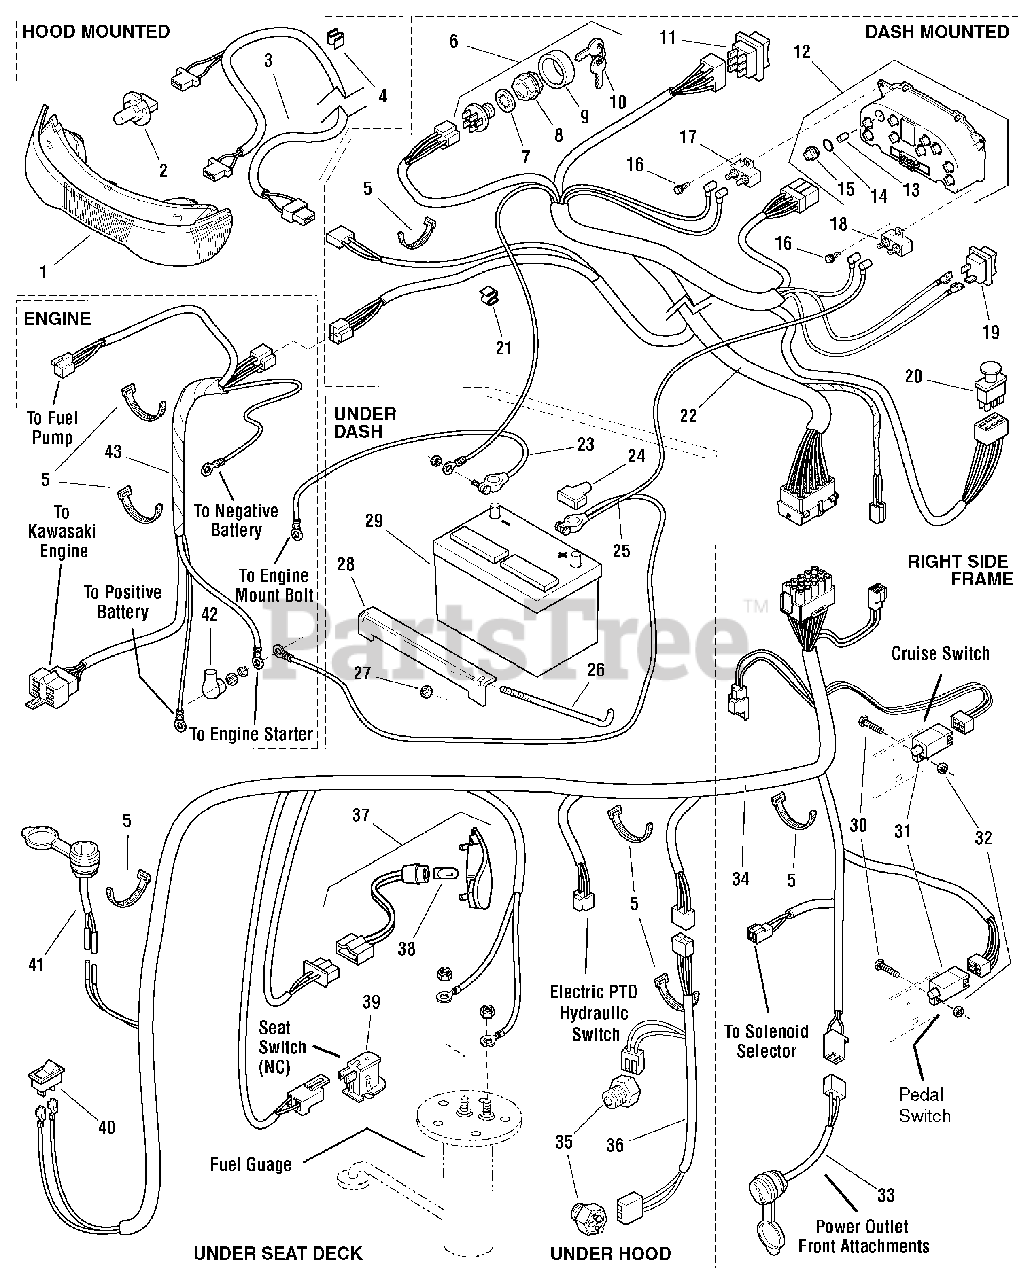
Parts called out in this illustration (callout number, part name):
1	HEADLIGHT ASSEMBLY
2	BULB, Headlight Halogen
3	HARNESS, Wiring, Headlight
4	CLIP, Wire
5	TIE, Self Locking
6	SWITCH ASSEMBLY, Ignition
7	LOCKWASHER, Internal Tooth
8	NUT, Hex, Flange, 5/8-32, Ignition Switch Die Cast
9	COVER, Ignition Switch
10	KEYS, Set of 2
11	SWITCH, Electrical Lift
12	PANEL, Instrument Air Cooled
12	PANEL, Instrument Liquid Cooled
13	BULB, Instrument Panel
14	SEAL, Lamp Socket Plug
15	HOLDER, Bulb (Includes Ref. No. 14)
16	SCREW, Hex Washer Head, 12-24 x 5/8
17	BREAKER, Circuit 12Volt, 10Amps
18	BREAKER, Circuit 12Volt, 20Amps with Tab 9/32
19	SWITCH, Headlights
20	SWITCH, PTO Push/Pull Symbols
22	HARNESS, Wiring
23	CABLE, 1 Ring, 1 Battery Terminal
24	INSULATOR, Battery Terminal
25	CABLE, 1 Ring, 1 Battery Terminal
27	NUT, Hex KEPS, 1/4-20 Conical Washer
28	BRACKET, Battery Hold Down
29	BATTERY, 12 Volt, 6 Cell, 500 Amps
30	SCREW, Hex Washer Head Slot 10-24 x 5/8
31	SWITCH, Push Button, Neutral, Start
32	NUT, Hex KEPS, 10-24
33	HARNESS ASSEMBLY, Power Outlet, 8" Long
34	HARNESS, Rear
35	SWITCH, Interlock Ball Check 5/16 Long Thread
36	HARNESS, PTO Lights
37	TAIL LIGHT ASSEMBLY
38	BULB, Tail Light
39	SWITCH, Push Button Foot Pedal
40	SWITCH, Rocker Solenoid, Select
41	OUTLET, 12 Volt
42	BOOT, Cable Terminal
43	HARNESS, Jumper
